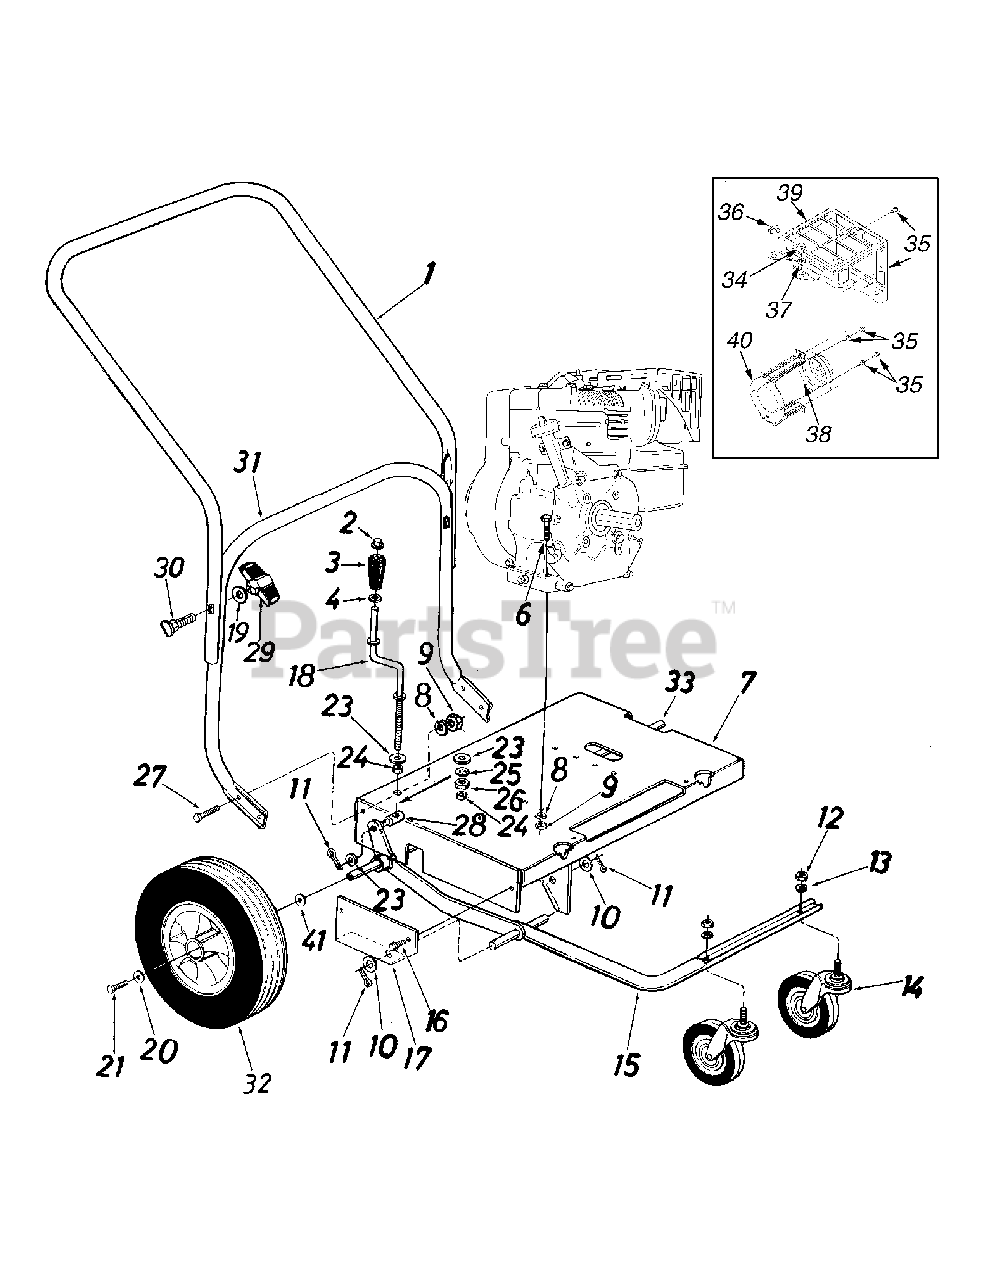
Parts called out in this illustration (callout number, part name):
2	Push Nut 3/8
3	Crank Knob
4	Flat Washer.385 ID x.62 OD
6	Hex Bolt 5/16-18 x 1.50
9	Hex Nut 5/16-18
10	Flat Washer.63 ID x 1.25
11	Cotter Pin
12	Hex Nut 1/2-13
13	Lock Washer 1/2
14	Swivel Caster Wheel 5" Dia x 1.25
19	Saddle Washer.32 ID x.93 OD
20	Flat Washer.34 ID x.87 OD
21	Hex Lock Bolt 5/16-24 x.64
23	Flat Washer.38 ID x.57 OD
24	Spacer.382 ID x.50 OD x.180Lg
25	Lock Washer 3/8 ID
26	Hex Nut 3/8-8
27	Hex Bolt 5/16-18 x.75
28	Ferrule
29	Hand Knob
30	Carriage Bolt 5/16-18 x 2.0
33	Rear Axle
34	Self Tap Screw 1/4-20 x.5 (if equipped)
35	Screw 8-18 x.375 (if equipped)
36	Hex Lock Nut 5/16-18 (if equipped)
37	Lock Washer (if equipped)
38	Deflector (if equipped)
39	Muffler Guard (if equipped)
40	Muffler Guard Bracket (if equipped)
41	Flat Washer
42	Hex Lock Nut 5/16-18
